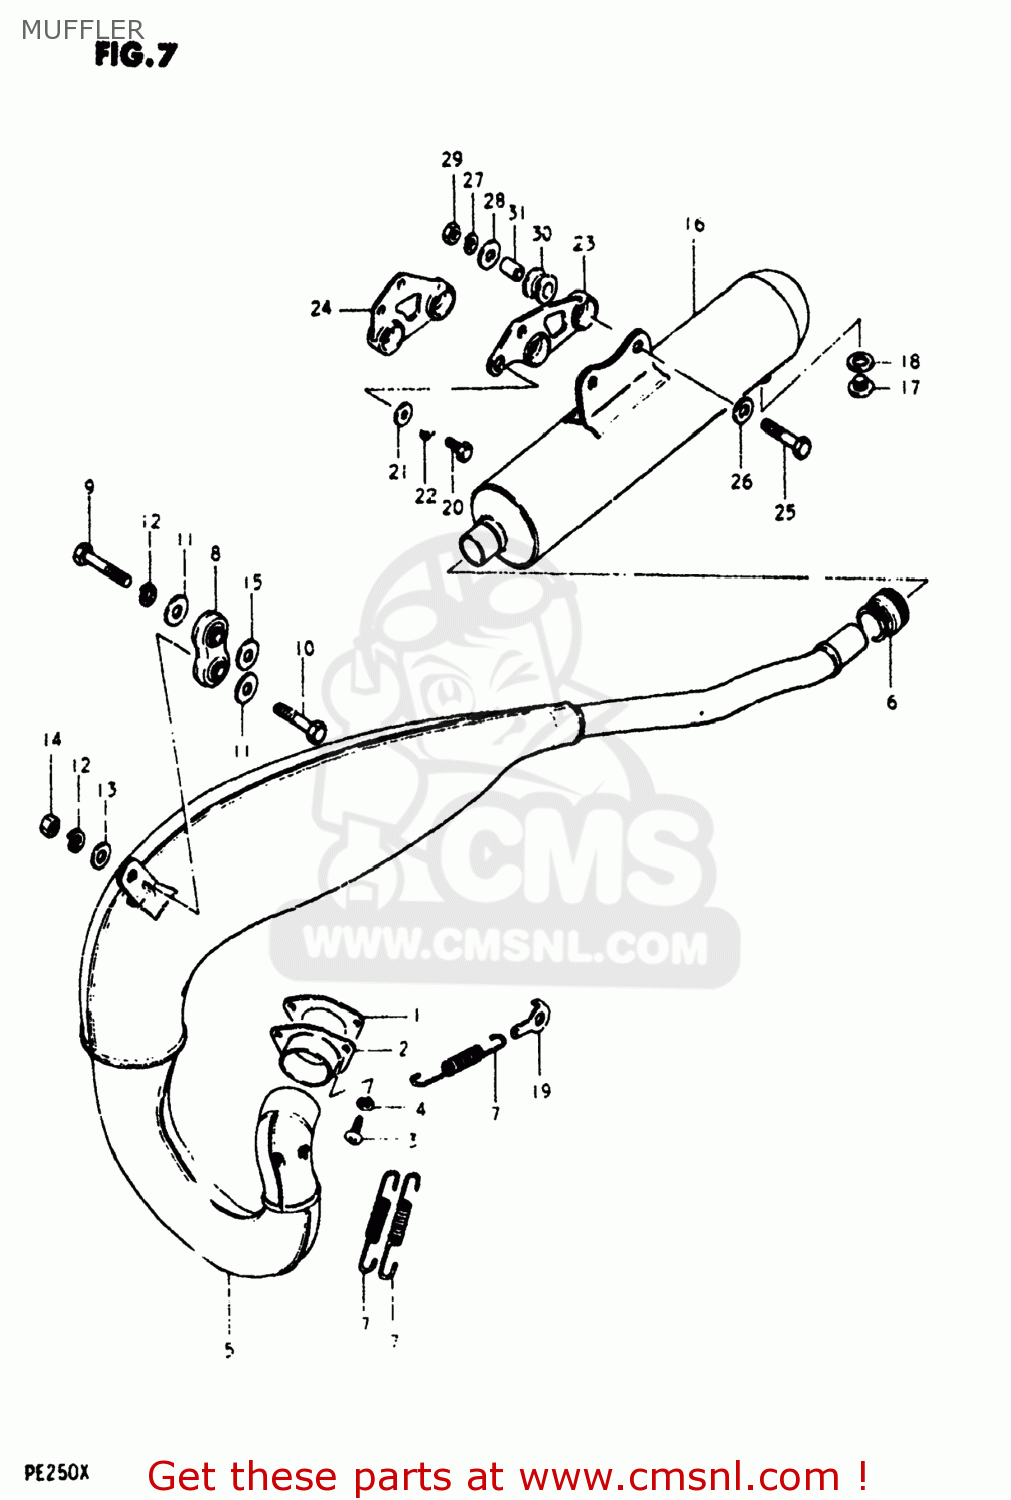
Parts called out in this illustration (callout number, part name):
1	GASKET,EXHAUST PIPE (MCA)
2	FLANGE,EXHAUST PIPE
3	SCREW
4	LOCK WASHER
5	BODY,MUFFLER
6	CONNECTOR,MUFFLER
7	SPRING
8	DAMPER,MUFFLER
9	BOLT 8X45
10	BOLT
11	WASHER
12	LOCK WASHER
13	WASHER
14	NUT
15	SPACER(8.4X12X12)
16	MUFFLER ASSEMBLY
17	PLUG(12X9)
18	GASKET(12X16X2) (NAS)
19	HOOK,MUFFLER FIT SPRING
20	BOLT
21	WASHER
22	LOCK WASHER
23	DAMPER,MUFFLER SUPPORT
24	DAMPER,MUFFLER SUPPORT
25	BOLT
26	WASHER
27	LOCK WASHER
28	WASHER (8.5X29X1.6)
29	NUT
30	CUSHION
31	SPACER (8.2X12X17)
